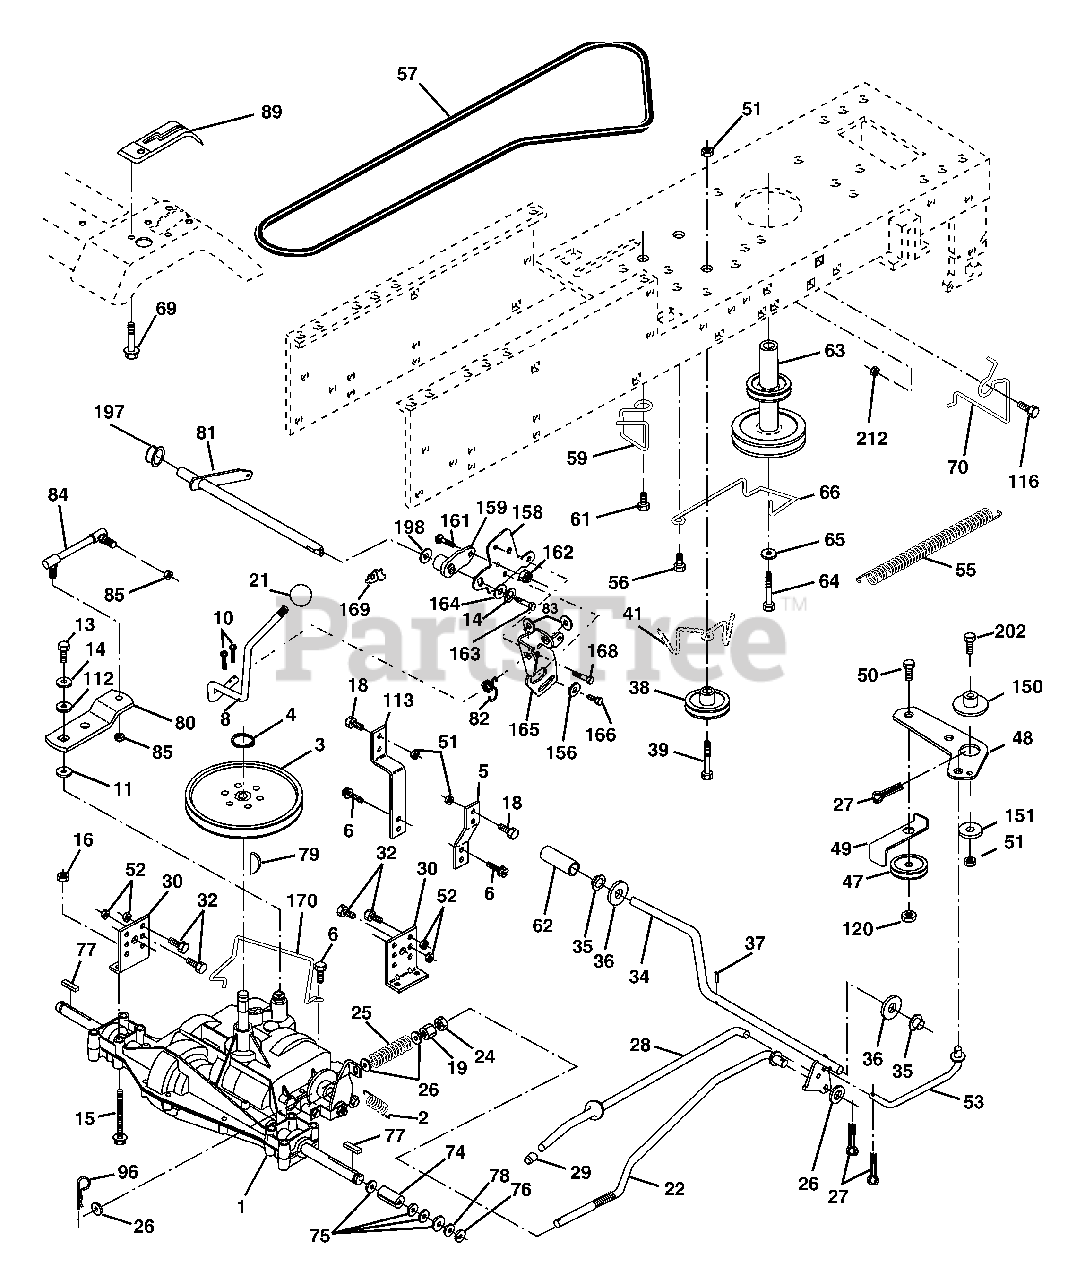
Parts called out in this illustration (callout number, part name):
2	Spring Return Brake T/a Zinc
3	Pulley Transaxle 18" tires
4	Ring Retainer # 5100-62
5	Strap Torque 30 Degrees
6	Screw 5/16-18 X 3/4
8	Rod Shift Fender Adjust Lt
10	Pin Cotter 1/8 X 1 Cad
11	Washer Plate Shf 388 Sq Hole
13	Bolt 1/4-28 Unf Gr 8 W/Patch
14	Washer Lock Hvy Helical
15	Bolt Hex FLGHD 5/16-18 Gr. 5
16	Nut Lock Hex w/ins 5/16-18
18	Bolt, Fin Hex 3/8-16 UNC x 1 Gr. 5
19	Nut Lock 3/8-16 Unc
21	Knob
22	Rod Brake Blk Zinc 26 840
24	Nut Hex Jam 3/8-16 Unc
25	Spring Rod Brake 2 00 Zinc
26	Washer 13/32 X 13/16 X 16 Ga
27	Pin Cotter 1/8 X 3/4 Cad
28	Rod Brake Parking LT/YT
29	Cap Brake Parking
30	Bracket Mtg Transaxle
32	Bolt Hex Hd 5/16-18unc X 3/4
34	Shaft Asm Pedal Foot
35	Bearing Nylon Blk 629 Id
36	Washer 21/32 X 1 X 16 Ga
37	Pin Roll 3/16 X 1"
38	Pulley Composite Flat
39	Bolt Fin Hex 3/8-16 unc X 3
41	Keeper Belt Flat Idler
47	Pulley Idler V Groove Plastic
48	Bellcrank Asm
49	Retainer Belt Style Spring
50	Bolt Carr. Sh. 3/8-16 x 1-1/2 Gr. 5
51	Nut Crownlock 3/8-16 Unc
52	Nut Crownlock 5/16-18 Unc
53	Link Clutch
55	Spring Return Clutch 6 75
56	Screw 3/8-16 x 1-1/4
57	V-Belt Ground Drive 95 30
59	Keeper Belt Span Ctr
61	Screw 3/8-16 x .875
62	Cover Pedal Blk Round
63	Engine Pulley
64	Bolt Hex
65	Washer Lock Hvy Hlcl Spr 7/16
66	Keeper Belt Engine Foolproof
69	Screw Hex wsh Hi Lo 1/4 x 1/2 unc
70	Guide Belt Mower Drive RH
74	Spacer Axle
75	Washer 25/32 X 1 1/4 X 16 Ga
76	E-ring #5133-75
77	Key Square 2 0 X 1845/ 1865
78	Washer 25/32 X 1-5/8 X 16 Ga
79	Key Woodruff #9 3/16 x 3/4
80	Arm Shift
81	Shaft Asm Cross Tapered PMST/20
82	Spring Torsion T/a
83	Washer 17/32 X 3/4 X 16 Ga
84	Link Transaxle PMST/18" Zinc
85	Nut Lock Center 1/4 - 28 FNTHD
89	Console Shift STLT
96	Retainer Spring 1"
112	Washer 9/32 x 3/4 x 10 Ga.
113	Strap Torque LT
116	Bolt Rdhd Sq Neck 3/8-16 x 1
120	Nut Lock Flg. 3/8-16 Unc
150	Spacer Retainer
151	Washer 13/32 x 2 x 10
156	Washer Srrted 5/16 ID x 1.125
158	Bracket Shift Mount
159	Hub Tapered Flange Shift Lt
161	Bolt Rdhd Sqnk 1/4-20 x 3/4 Gr
162	Nut Crownlock 1/4-20 Unc
163	Bolt Hex Fin 1/4-20 Unc x 1 Gr 5
164	Washer 5/8 x .281 x 10 Ga
165	Bracket Pivot Lever
166	Screw 5/16-18 x 5/8
168	Bolt Shoulder 5/16-18 x .561
169	Plate Fastening
170	Keeper Belt Transaxle Gear
197	Nyliner Snap-In
198	Washer Nyliner
202	Bolt Rd Hd 3/8-16 Unc x 1-3/4 Gr. 5
212	Nut Hex flange Lock
